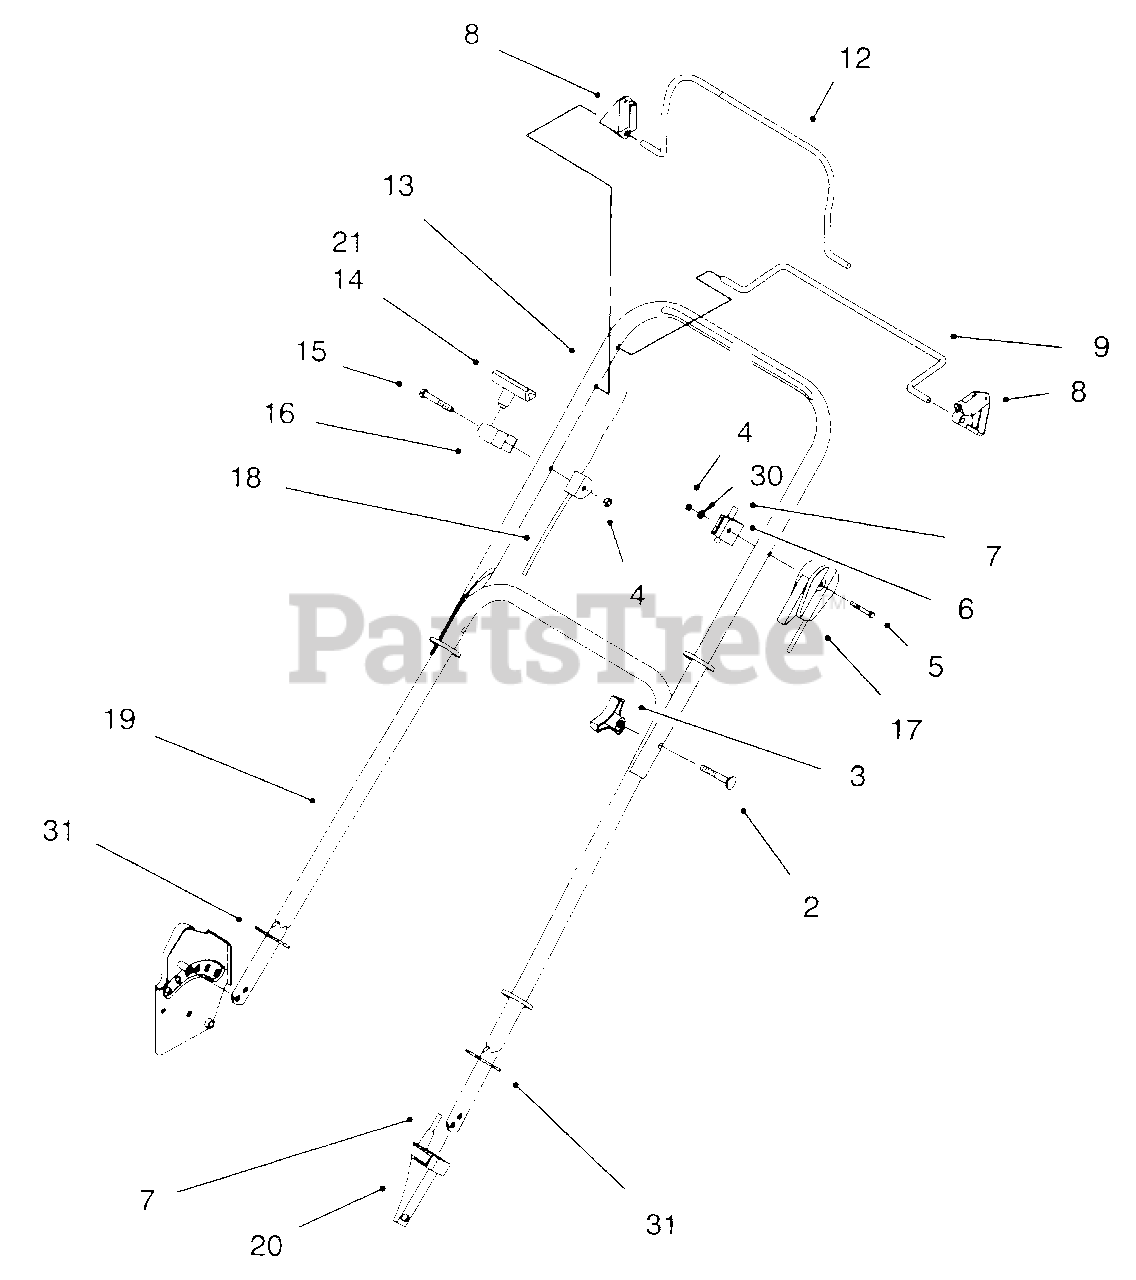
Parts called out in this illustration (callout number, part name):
2	Screw-Handle
3	Knob
4	Nut-Lock
5	Screw-Hex Hd. Cap (Model No. 10227 Only)
5	Screw-Hex Hd. Cap (Model No. 10304 Only)
6	Anchor-Cable Upper (Model No. 10304 Only)
7	Cable-Traction (Model No. 10304 Only)
8	Stop-Pivot (Model No. 10227 Only)
8	Stop-Pivot (Model No. 10304 Only)
9	Bail-SP Control (Model No. 10304 Only)
12	Bail-Flywheel Brake
13	Handle-Section Upper
14	Handle-Starter
15	Screw-Hex Hd. Cap
16	Guide-Rope
17	Cable-Throttle 2 Cycle
18	Cable-Flywheel Brake
19	Handle Section-Lower
20	Anchor-Cable SP Lower (Model No. 10304 Only)
21	Clip-Rope Insert
30	Washer (Model No. 10227 Only)
31	Handle-Guard (Model No. 10227 Only)
31	Handle-Guard (Model No. 10304 Only)
